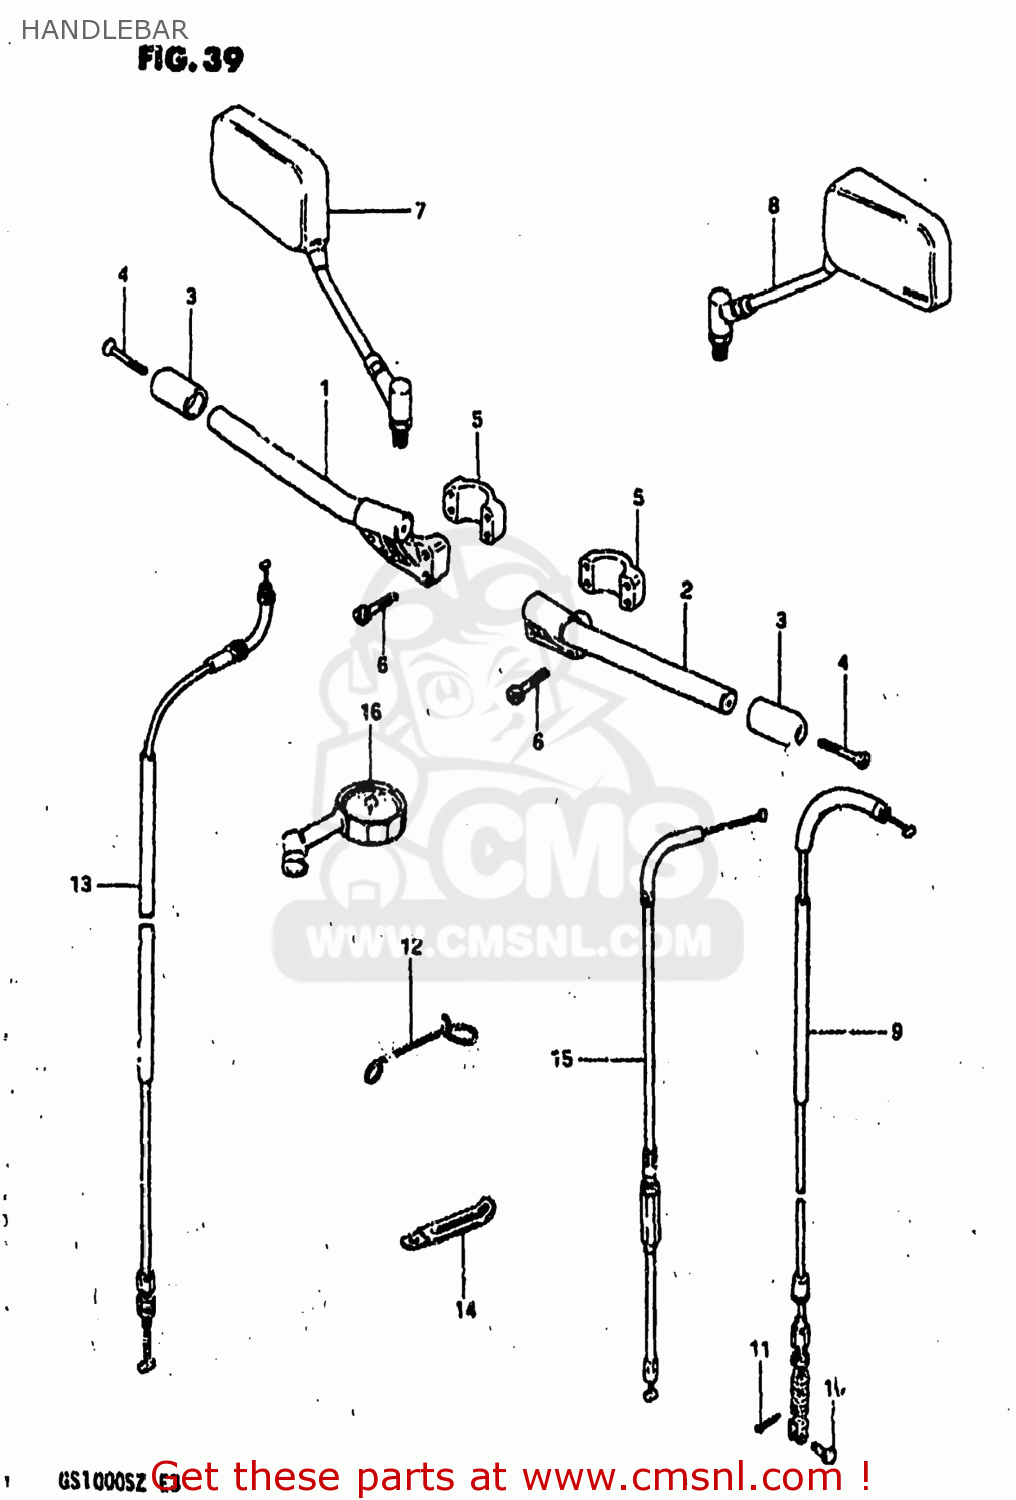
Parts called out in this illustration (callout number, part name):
1	HANDLEBAR,R
2	HANDLEBAR,L
3	BALANCER,HANDLEBAR
4	SCREW
5	HOLDER,HANDLEBAR
6	BOLT
7	SUZUKI
8	SUZUKI
9	CABLE, CLUTCH
10	PIN(L:15)
11	PIN
12	GUIDE,CLUTCH CABLE
13	CABLE ASSEMBLY,THROTTLE
14	CLAMP
15	CABLE,CLUTCH
16	GAUGE ASSY,AIR PRESSURE
